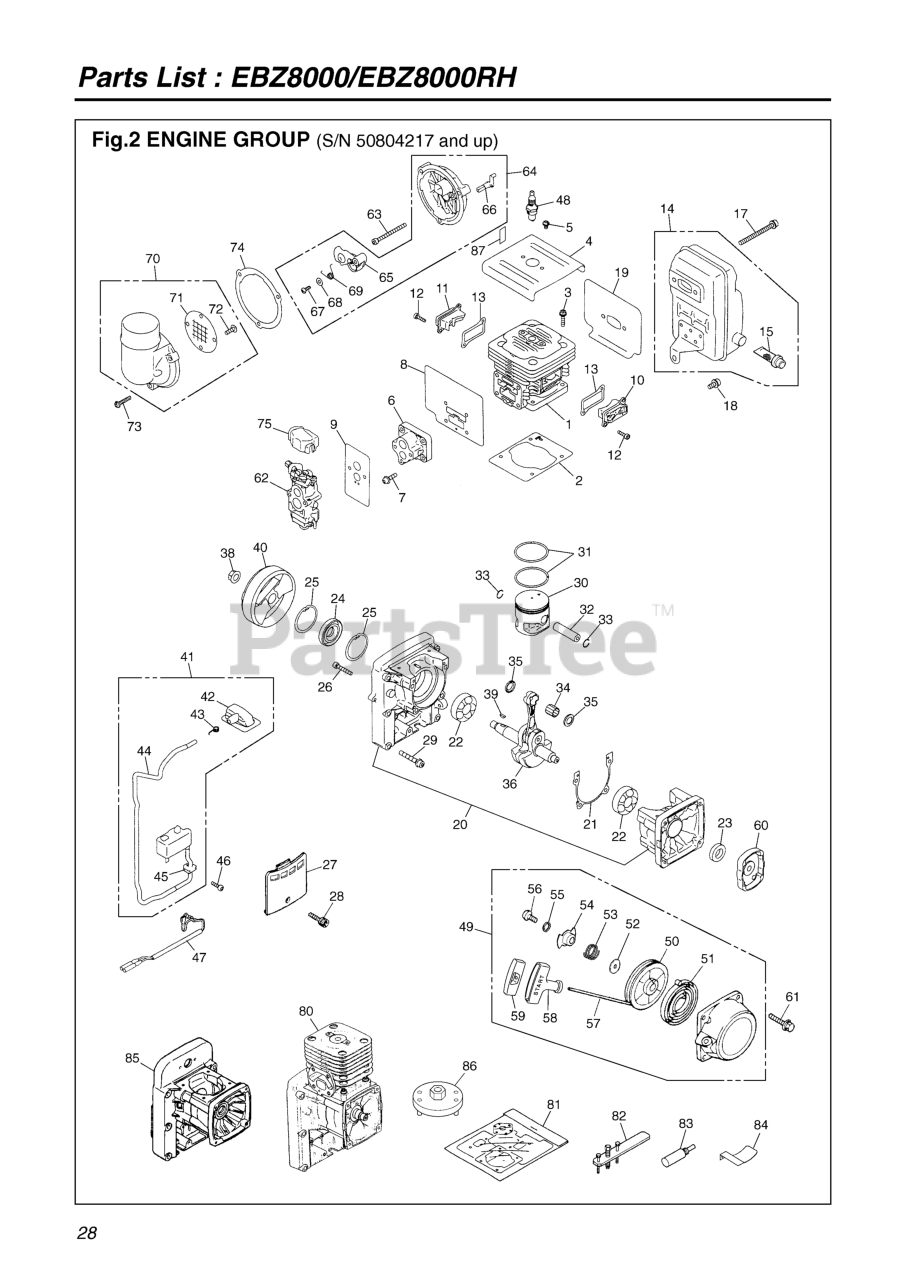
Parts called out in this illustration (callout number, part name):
1	CYLINDER (EBZ8000)
2	GASKET, BASE
3	BOLT
4	PLATE, CYL
5	SCREW TORX
6	INSULATOR
7	BOLT TORX
8	GASKET, INSULATOR
9	GASKET, CARB.
10	COVER, TR-S
11	COVER,TR-F
12	BOLT TORX
13	GASKET, TR
14	MUFFLER ASSY.
15	ARRESTER
17	BOLT
18	BOLT
19	GASKET, MUFFLER (RPLS. -15C0)
20	CRANKCASE-CASE
21	GASKET, CASE
22	BEARING
23	SEAL
24	SEAL
25	SNAP RING
26	BOLT
27	COVER
28	BOLT TORX
29	BOLT TORX
30	PISTON
31	RING
32	PIN
33	SNAP RING
34	BEARING
35	WASHER
36	CRANKSHAFT-C
38	NUT, M10
39	KEY
40	ROTOR
41	COIL-A
42	CAP
43	SPRING
44	TUBE
45	GROMMET
46	BOLT TORX
47	CORD-C
49	RECOIL ASSY (RPLS -7511)
50	REEL (REPLACES -75C1)
51	SPRING
52	WASHER (REPLACES -75M0)
53	SPRING, FRICTION (RPLS. -75L1)
54	PLATE, FRICTION (RPLS. -75K1)
55	WASHER (REPLACES -75W0)
56	SCREW
57	ROPE
58	KNOB
59	COVER KNOB
60	PULLEY (RPLS 848-H00-7520)
61	BOLT, TORX
62	CARBURETOR-A (WYA-44)
63	BOLT
64	CUP ASSY. (REPLACES -8330)
65	PLATE, CHOKE (REPLACES -83C1)
66	LEVER
67	SCREW
68	WASHER
69	SPRING
70	COVER ASSY. (REPLACES -8340)
71	SCREEN
72	SCREW
73	SCREW
74	GASKET,CUP
75	COVER
80	SHORT BLOCK (EBZ8000)
81	GASKET KIT
82	PULLER ASSY
83	STOPPER (TOOL)
85	CRANKCASE-A
86	PULLER
87	LABEL, CHOKE
